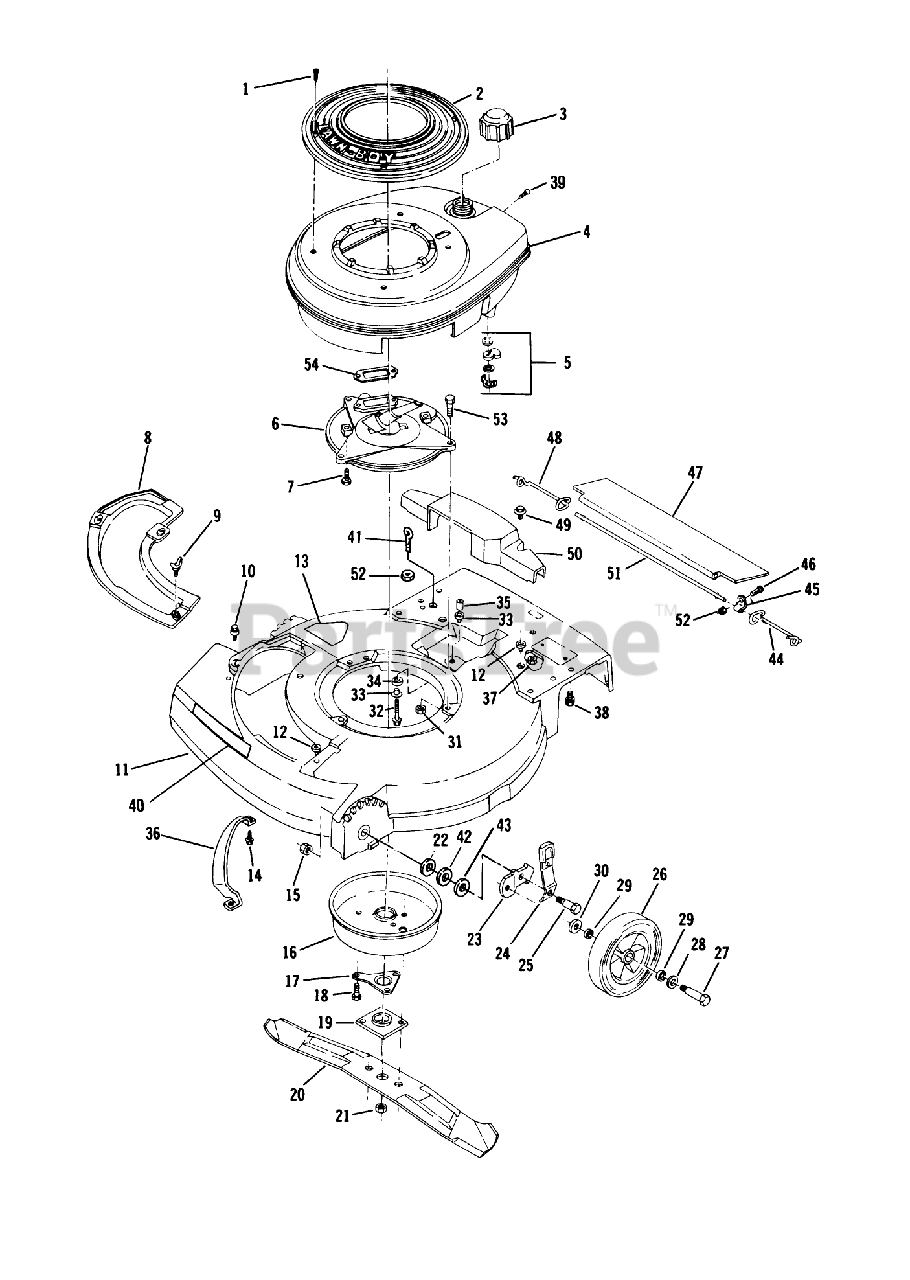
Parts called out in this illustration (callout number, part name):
1	SCREW - SELF TAPPING
3	FUEL CAP & INSERT
5	SHUT OFF VALVE KIT
6	PLATE F
7	SCREW V
9	WING SCREW LAWRE
16	MUFFLER COVER F
17	SUPPORT F
18	SCREW
19	PLATE AND COLLAR ASM
21	NUT-BLADE
22	WASHER
24	SPRING ARM ASM
25	BOLT
26	WHEEL & TIRE KIT
27	BOLT WHEEL
28	SPACER
29	WASHER
30	WASHER WROUGHT
31	NUT-LOCK F
33	SPACER ECK PRES
34	GROMMET
35	SPACER
36	BAR-TOE
38	SCREW
39	SCREW S
41	BOLT-EYE
42	WASHER
43	WASHER
44	SPRIG T/SHLD ASOC
45	CLAMP ROD KMC
47	SHIELD
48	SPRING;TRAILING SHIELD RH
49	SCREW SEMS TRM HEX HD
51	ROD 21" ADVANCE
52	LOCKNUT E
53	SCREW-HH
